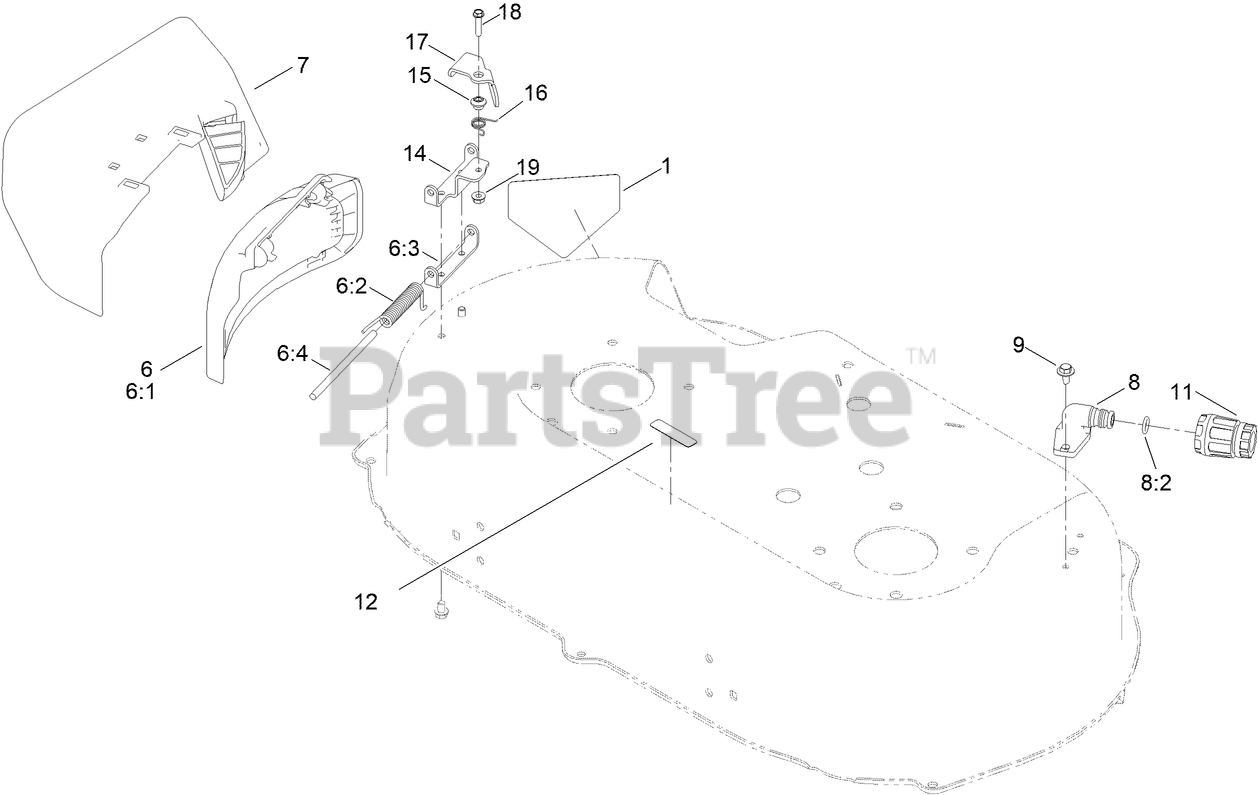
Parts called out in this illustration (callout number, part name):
1	DECAL-DANGER
6	SIDE DEFLECTOR SERVICE ASM
6:1	DEFLECTOR-DISCHARGE, SIDE
6:2	SPRING-TORSION, COVER
6:3	BRACKET-LOCKOUT
7	SIDE DISCHARGE CHUTE ASM
8	FITTING-WASHOUT
8:2	O-RING
9	SCREW-HWH, THD ROLL
11	CONNECTOR-HOSE
12	DECAL-WARNING
14	BRACKET-LOCKOUT
15	SPACER
16	SPRING-TORSION
17	LEVER-LOCKOUT
18	SCREW-HWH
19	NUT-HEX FLANGE
